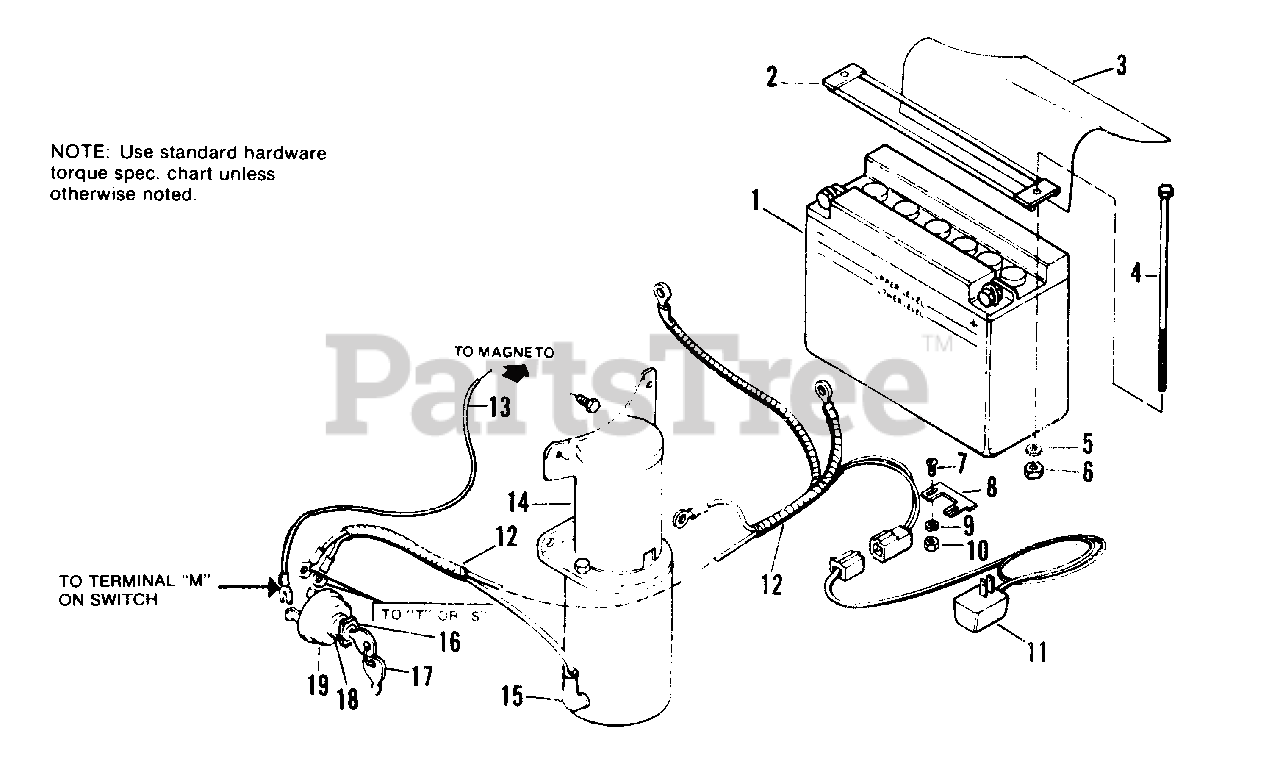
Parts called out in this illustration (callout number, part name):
2	HOLD DOWN, Battery
3	INSULATION, Battery
4	CAPSCREW, Hex Hd., 1/4-20 x 6-1/2
5	LOCKWASHER, 1/4
6	NUT, Hex, Full, 1/4-20
7	SCREW, Machine, #10-32 x 1/2
8	CLIP, Mounting
9	LOCKWASHER, Ext., #10
10	NUT, Hex, Full, #10-32
11	CHARGER ASSY.
12	HARNESS ASSY.
13	WIRE (Switch to Magneto)
14	STARTER KIT
15	COVER, Terminal
16	NUT, Hex, Special
18	LOCKWASHER, Int., 5/8
19	SWITCH, W/Keys
